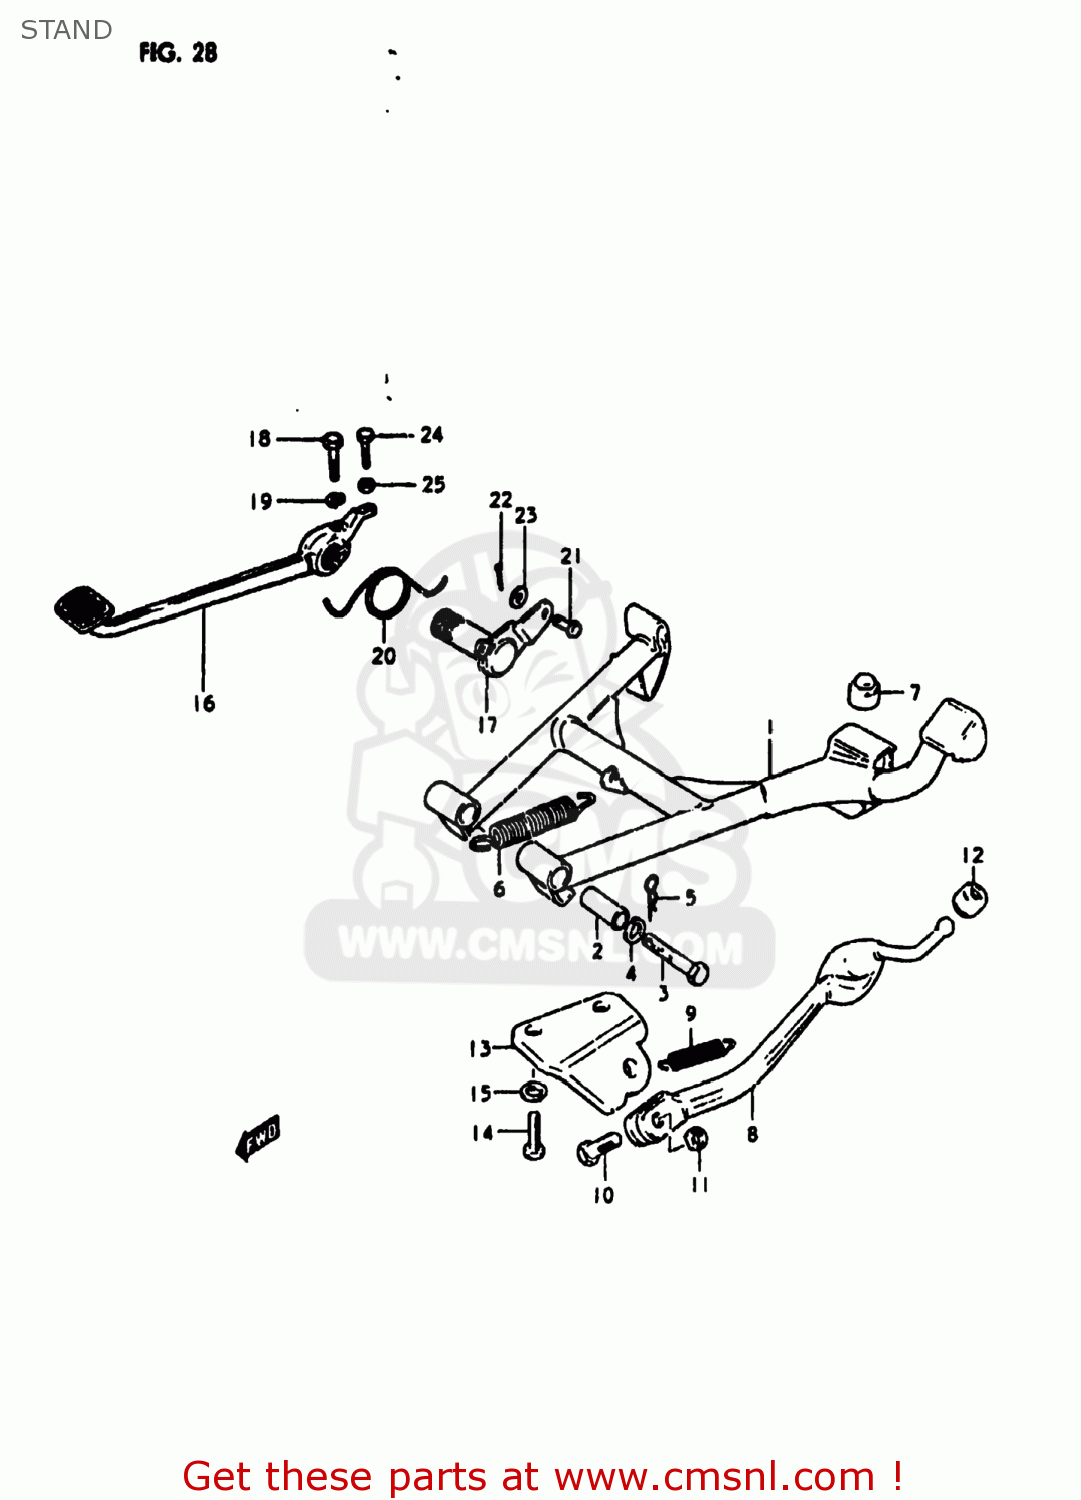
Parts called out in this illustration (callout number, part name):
1	STAND,CENTER
2	SPACER(10X16X38.8)
3	BOLT
4	LOCK WASHER
5	CLIP
6	SPRING
7	CUSHION
8	STAND,PROP
9	SPRING
10	BOLT
11	NUT
12	CUSHION
13	BRACKET,SIDE STAND
14	BOLT
15	LOCK WASHER
16	PEDAL,BRAKE
17	ARM,BRAKE PEDAL
18	BOLT
19	LOCK WASHER
20	SPRING
21	PIN
22	PIN
23	WASHER
24	BOLT
25	NUT
